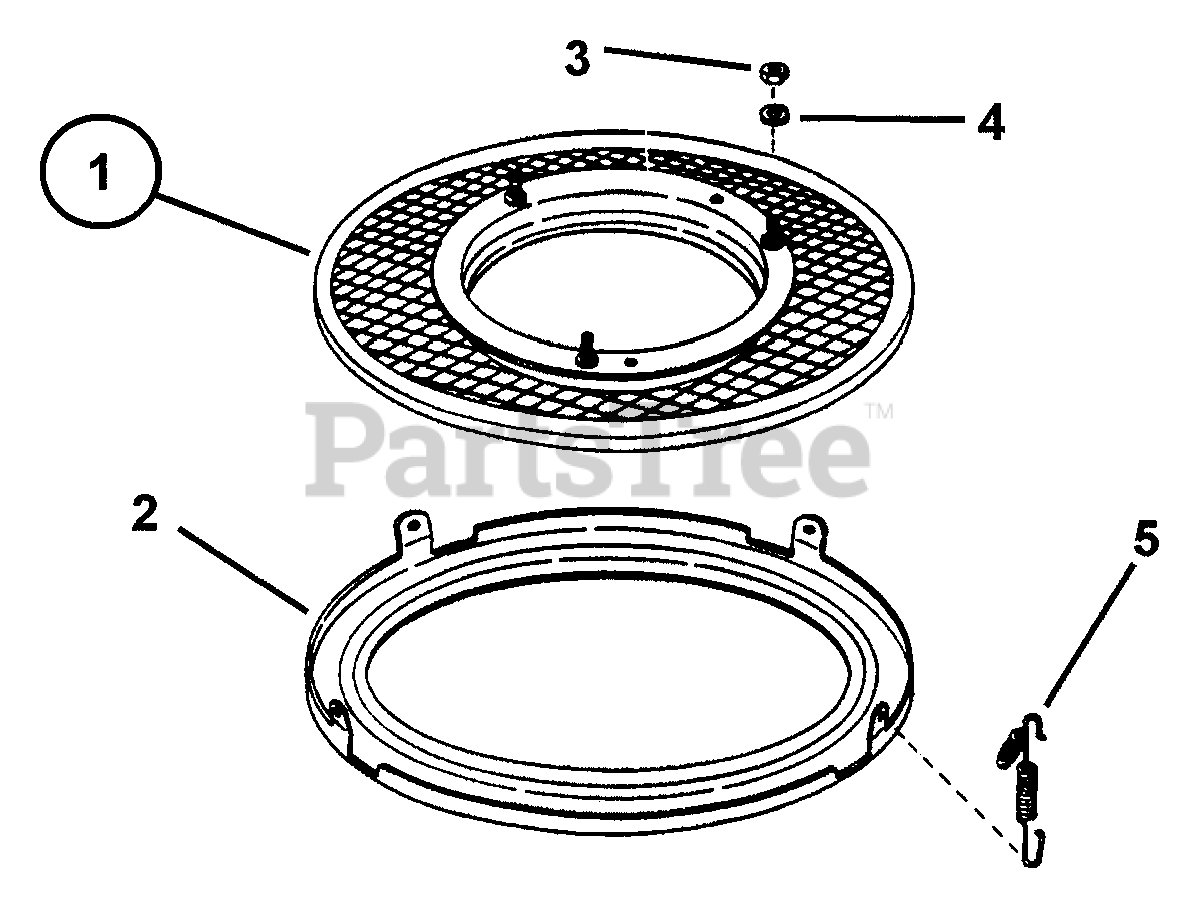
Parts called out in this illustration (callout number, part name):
1	SCREEN, Fastener Assembly
2	RING, Bottom
3	NUT, 5/16-24 Hex, Grade 5
4	WASHER, 5/16 Split Lock
5	SPRING
